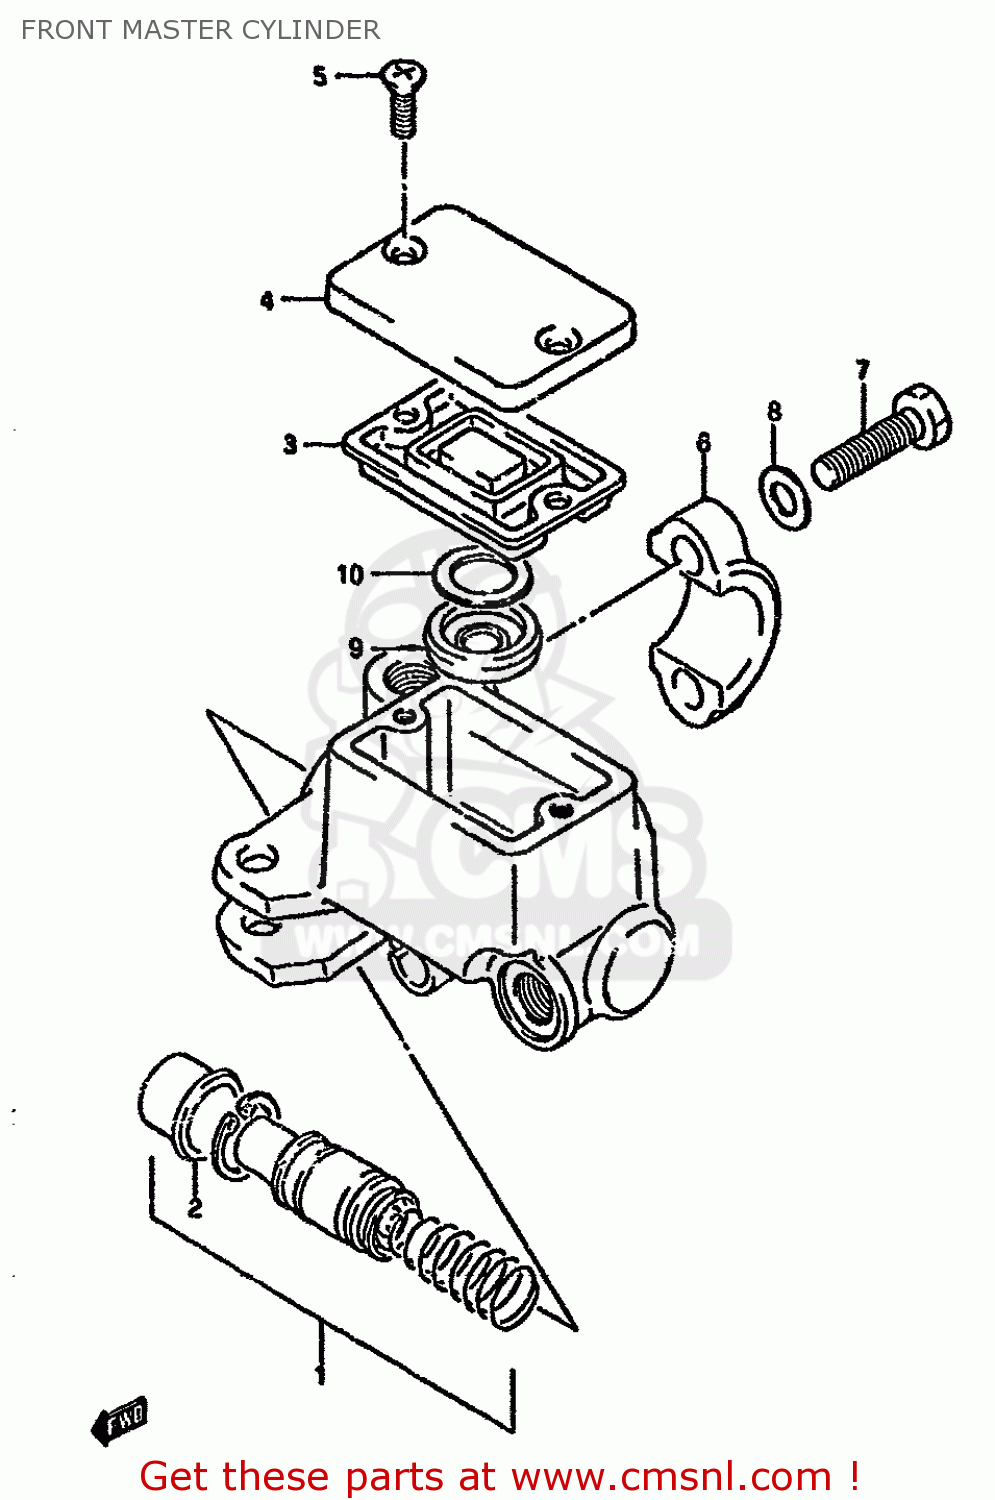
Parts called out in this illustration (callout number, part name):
1	PISTON/CUP SET
2	BOOT
3	DIAPHRAGM
4	CAP
5	SCREW
6	HOLDER
7	BOLT
8	WASHER
9	SEPERATOR
10	PLATE
